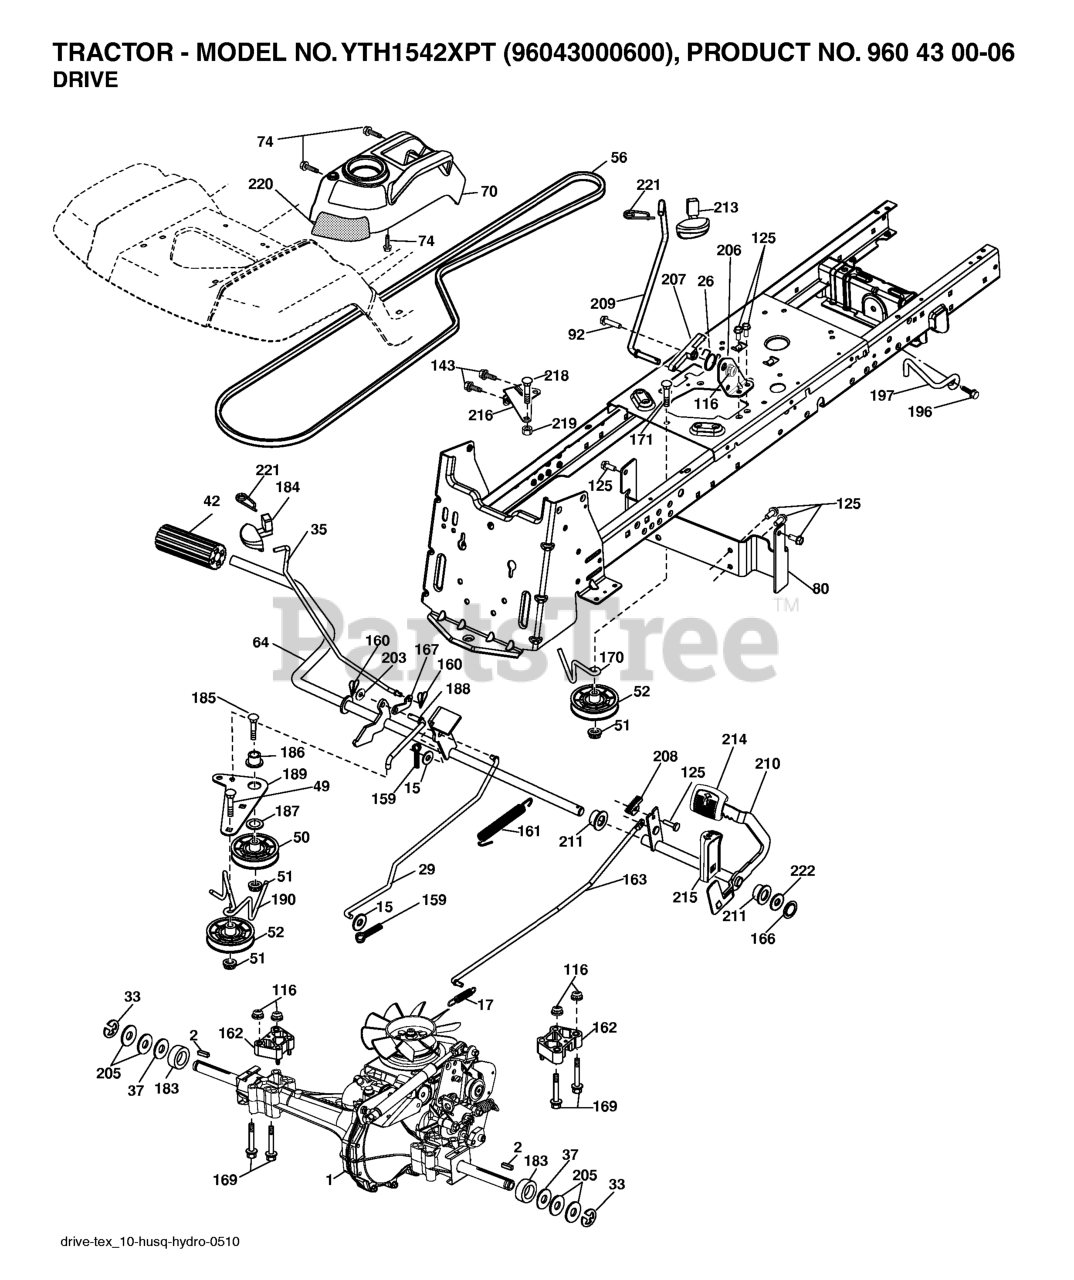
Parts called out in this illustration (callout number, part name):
2	SQUARE KEY
15	WASHER
17	SPRING.BRAKE.HG3000/3500
26	SPRING.RETURN.CRUISE
29	ROD.BRAKE.0610.PEDAL.CONTROL
35	ROD.BRAKE.PARKING.GT.H
42	PEDAL COVER T
50	IDLER.FLAT.910.OFFSET
51	NUT LOCK FLG 3/8-16 UNC
52	IDLER.V-GROOVE.910.OFFSET
64	SHAFT.ASM.PEDAL.BRK.CNTR
70	RP CONSOLE.ASM.PCH.W/TB
74	SCREW.HI-LO.CONSOLE
80	BRKT.STRP.TRQ.LT.HYD.C
92	BOLT
116	NUT LOCK HEX FLANGE 5/16-18
125	SCREW
143	Screw 5/16-18 x 1/2 Hex, Self Tapping 5/16-18 x 1/2
159	COTTER PIN
160	RETAINER CLIP
161	SPRING.RETURN.CLUTCH.2006
162	SPACER.TRANSAXLE.18&22
163	ROD.PEDAL.CONTROL.0510
166	NUT.PUSH.625.2006
167	LATCH.BRAKE.SPRING
169	BOLT.HEX.FLNG.5/16-18X3.75
170	KEEPER.V-IDLER.CENTER.
183	SPACER AXLE
184	HANDLE.PARKG.BRK.HUSQ X667
186	SPACER.RETAINER
187	WASHER 12/32X2X10GA
188	RP.LINK.CLUTCH.GROUND.DRIVE
189	BELLCRANK.GROUND.DRIVE.TEX.
190	KEEPER.BELLCRANK.DRIVE
196	SCREW 3/8-16X1
197	LINK.CLUTCH.ANIT-ROTAT
203	WASHER
206	BRKT.MOUNT.LATCH.CRUIS
207	LATCH.CONTROL.CRUISE
208	GEAR.SECTOR.CONTROL.CR
209	ROD.CONTROL.CRUISE.GT.
210	ROCKER.ASM.PEDAL.CONTR
211	BEARING.NYLON
213	KNOB.CONTROL.CRUSIE.HU
214	PEDAL.FORWARD.TEX.GT.4
215	PEDAL.REVERSE.TEX.GT.4
216	BRACKET.PULLEY.IDLER.W/TEX
218	BOLT.5/16-18X1-1/4 FULL.THREAD
219	SPACER.FENDER
220	REFLECTOR.RH.TEX GT
221	RETAINER.SPRING.CLIP.H
222	WASHER
